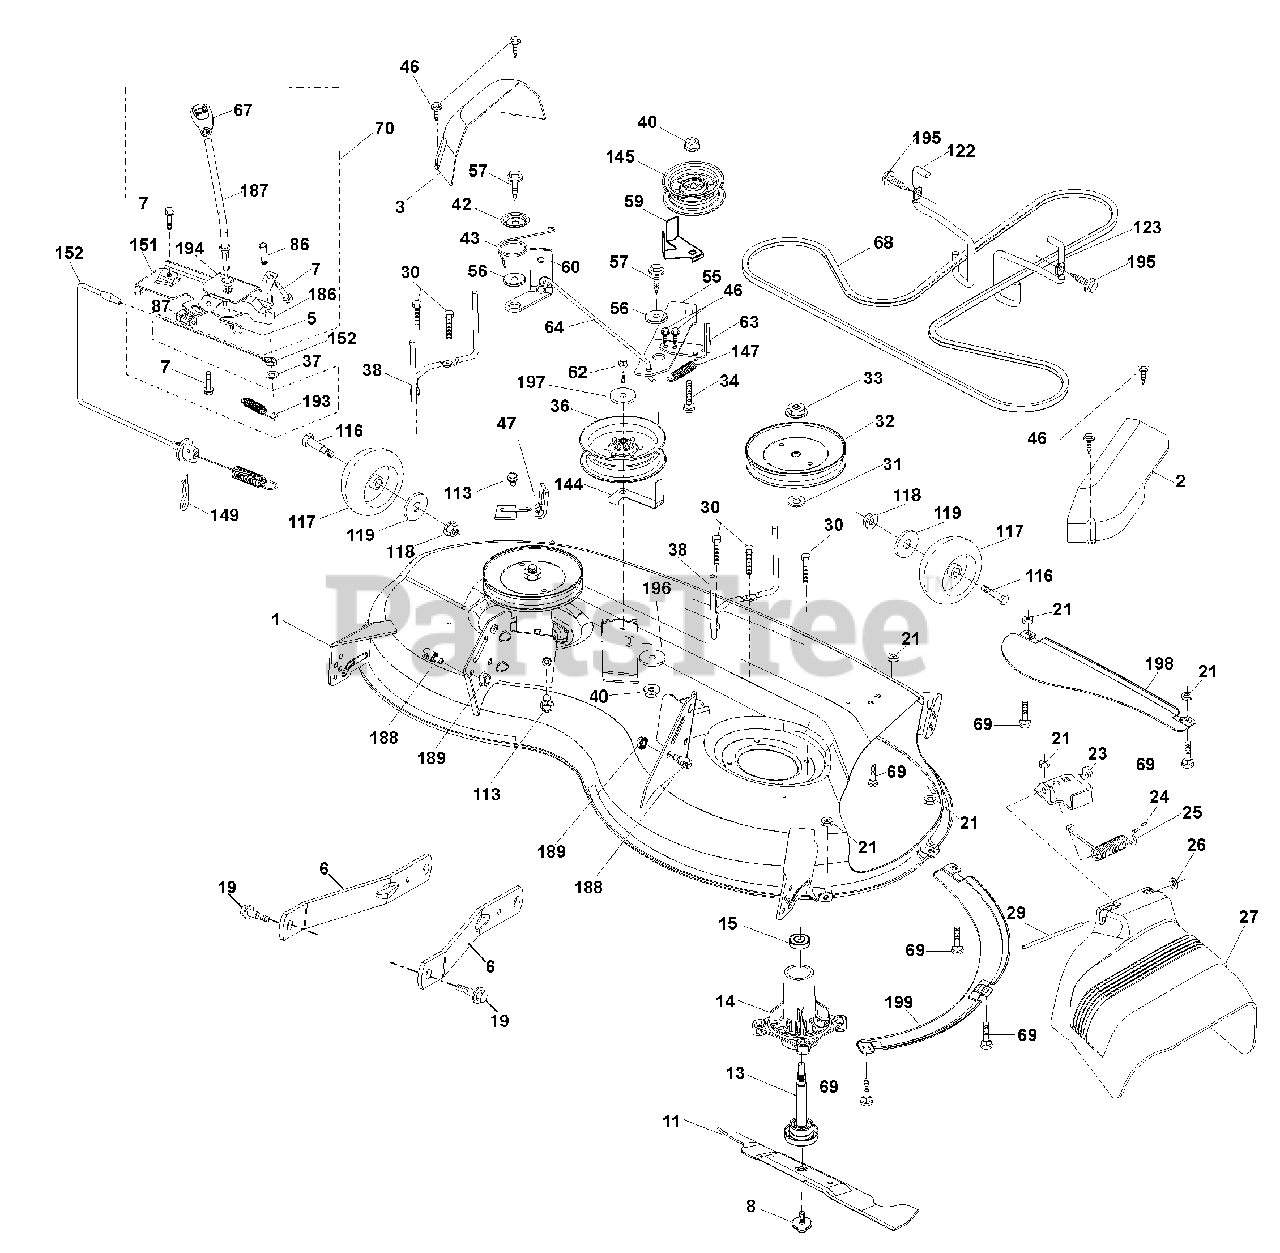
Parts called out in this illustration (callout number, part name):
1	Mower Housing
2	Cover Mandrel RH
3	Cover Mandrel LH
5	Retainer Spring
6	Arm Suspension
7	Screw 10 x 3/4 Single Hex
8	Bolt/Washer asm 7/16-20 unf
11	Blade Mower
13	Shaft Assembly, Mandrel
14	Housing, Mandrel
15	Bearing, Ball, Mandrel
19	Bolt, Shoulder
21	Nut
23	Bracket, Deflector
24	Cap, Sleeve
25	Spring, Torsion, Deflector
26	Nut, Push
27	Shield, Deflector
29	Rod, Hinge
30	Screw Thdrol Rolling Wsh Hd
31	Washer, Spacer
32	Pulley, Mandrel
33	Nut, Toplock, Flanged
34	Bolt Carr Sh. 3/8-16 x 1-1/2 Gr. 5
36	Pulley, Idler, Flat
37	Washer 13/32 x 13/16 x 16 Ga.
38	Keeper Belt LH Mandrel
40	Nut, Lock Flg. 3/8-16 unc
42	Spring Trosion Brake
43	Spring Torsion Retainer
46	Screw
47	Bracket Clutch Cable
55	Arm, Idler
56	Spacer, Retainer
57	Screw Hexwsh Thd 3/8-16 x 1
59	Guard, Tuv Idler (94)
60	Arm Brake Mower LH
62	Bolt 3/8-16 UNC x 2-1/4 Gr. 5
63	Arm Brake Mower
64	Linkage Brake
67	Handle, Clutch Cable
68	V-Belt
69	Bolt
70	Clutch Asm.
86	Pin Attachment Cable
87	Switch, Interlock Clutch
113	Screw 5/16-18
116	Bolt, Shoulder
117	Wheel, Gauge
118	Nut Centerlock 3/8-16 UNC
119	Washer 13/32 x 1-1/4 x 12 Ga.
122	Keeper Belt Eng. LH
123	Keeper Belt Eng. RH
144	Keeper Belt
145	Pulley Idler
147	Spring Return
149	Retainer Spring
151	Bracket Mount
152	Cable Clutch Manual w/Spr.
186	Arm Acutator CL Cable
187	Lever Control CL Cable
188	Stud Fastener
189	Nut Lock Hex Flange
193	Spring Plunger Actuator
194	Bearing Control Lever Clutch
195	Screw 3/8-16 x 3/4
197	Washer 13/32 x 13/16 x 12 Ga.
198	Baffle Center Front
199	Baffle Front RH
200	Washer 13/32 x 2 x 10 Ga.
200	Mandrel Assembly
200	Replacement Mower, Complete
